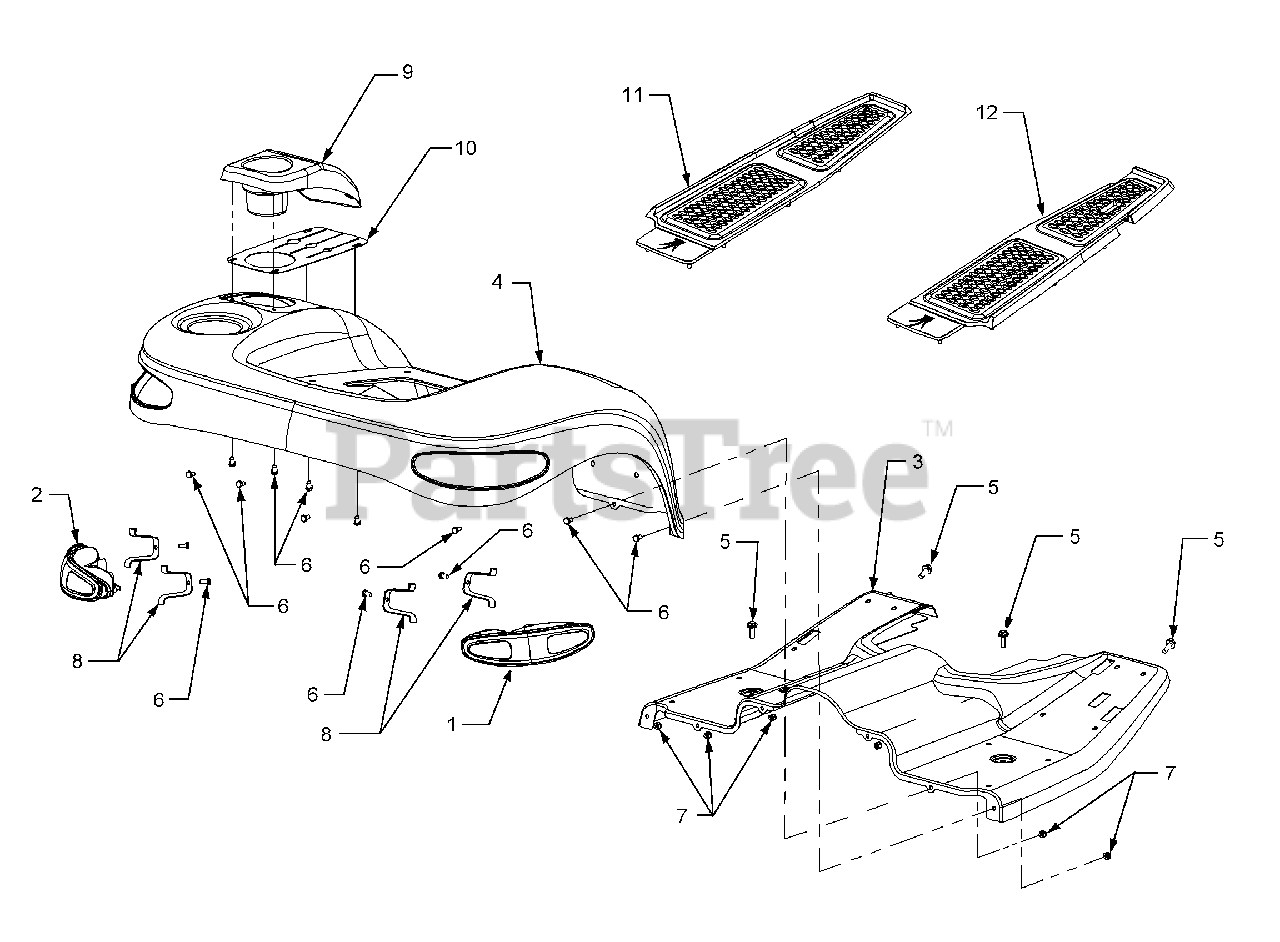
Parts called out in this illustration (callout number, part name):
1	Light Assembly, Rear RH
2	Light Assembly, Rear LH
3	Running Board
4	Fender
5	Screw, Hex Wash. Hd. Tapp 5/16-18 x 1.
6	Screw, Hex Cap, 1/4-20 x .5 GR5
7	Nut, Hex Lock, 1/4-20
8	Clip, Tail Light
9	Cover, Lift Lever
10	Flap, Lift Lever
11	Pad. Floor LH
12	Pad. Floor RH
